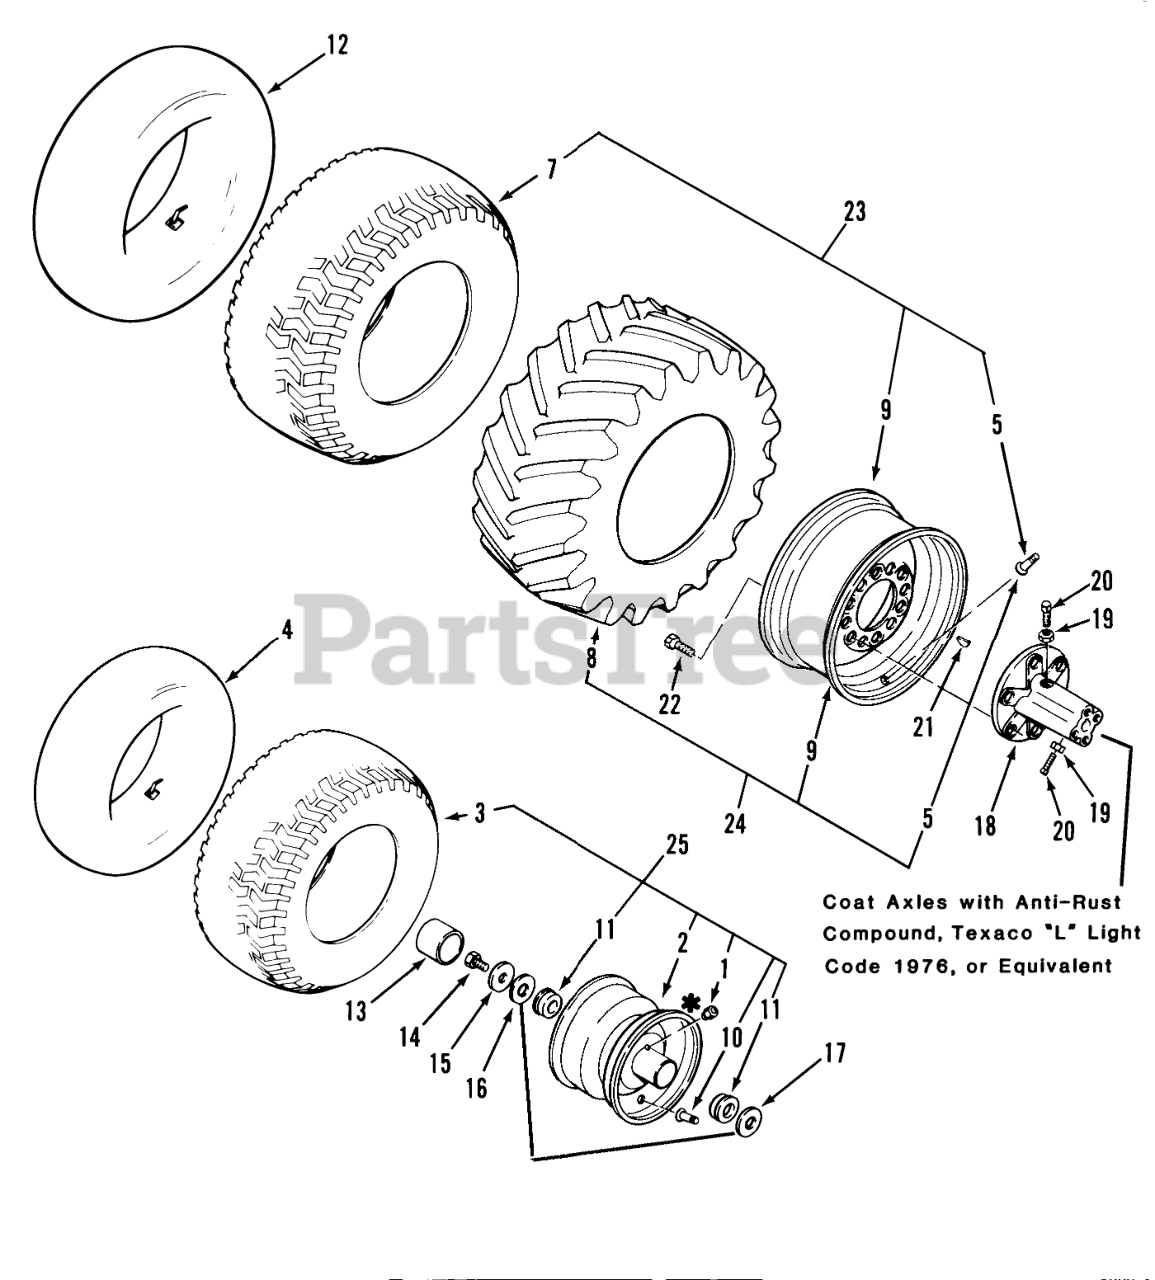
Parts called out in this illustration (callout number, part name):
1	Zerk
2	Front Wheel (Includes Item 1)
3	TIRE
4	TUBE-TIRE
5	VALVE TUBELESS
7	Tire 27 x 9.50-15
8	Rear Tire 27 x 8.50-15 Cleat
9	Rear Wheel
10	VALVE
11	BEARING WHEEL
12	Tube (Service Only)
13	HUBCAP
14	Bolt
15	WASHER
17	Washer
18	REAR HUB R
19	Nut
20	SS-SQ HD3/8-16X1 1/2
21	WOODRUFF KEY
22	LUG BOLT WHEEL 7/162
23	Rear Wheel and Tire Assy Turf
24	Right Rear Wheel and Tire Assy-Cleat
24	Left Rear Wheel and Tire Assy-Cleat
25	Front Wheel and Tire Assy
